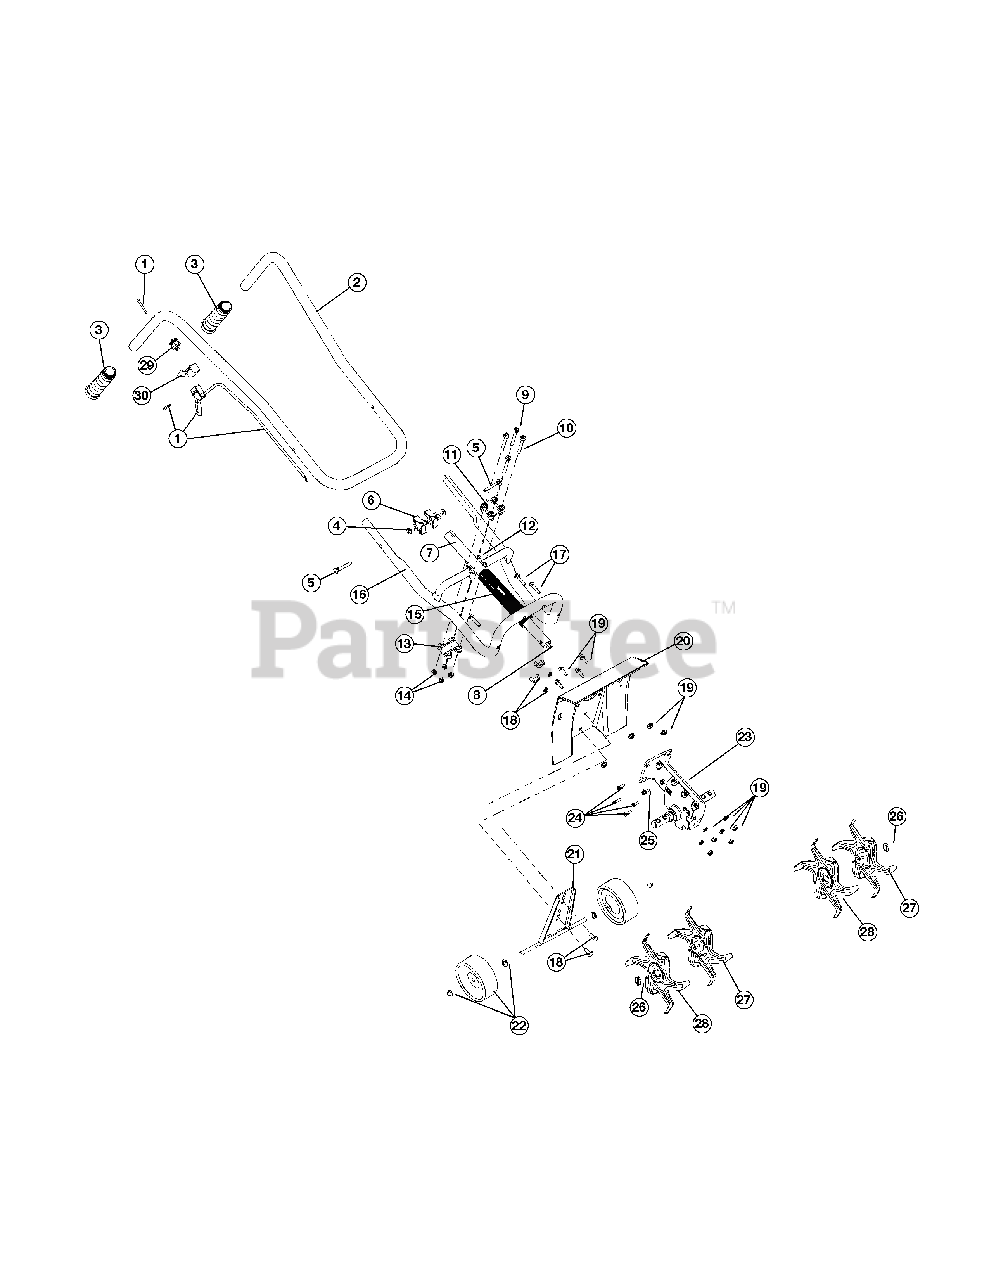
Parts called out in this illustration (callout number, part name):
1	Throttle Trigger Assembly
2	Handle Bar Assembliy, Upper (includes 3)
4	Washer
6	Knob, 3 prong
7	Drive Shaft Housing Assembly
8	Flexible Drive Shaft
9	Handle Bracket Assembly (includes 10-14)
11	Upper Handle Clamp
12	Middle Handle Clamp
13	Lower Handle Clamp
16	Lower Handle Bar
17	Hardware, Handle Bar Mounting (lower)
18	Wheel Bracket Mounting Hardware
19	Guard Mounting Hardware
21	Wheel Bracket Assembly
22	Wheel Assembly
23	Gear Box Assembly
25	Sleeve Retainer Bolt
26	Click Pin
27	Tine Assembly (Left Outer or Right Inner)
28	Tine Assembly (Left Inner or Right Outer)
30	Switch Bracket
